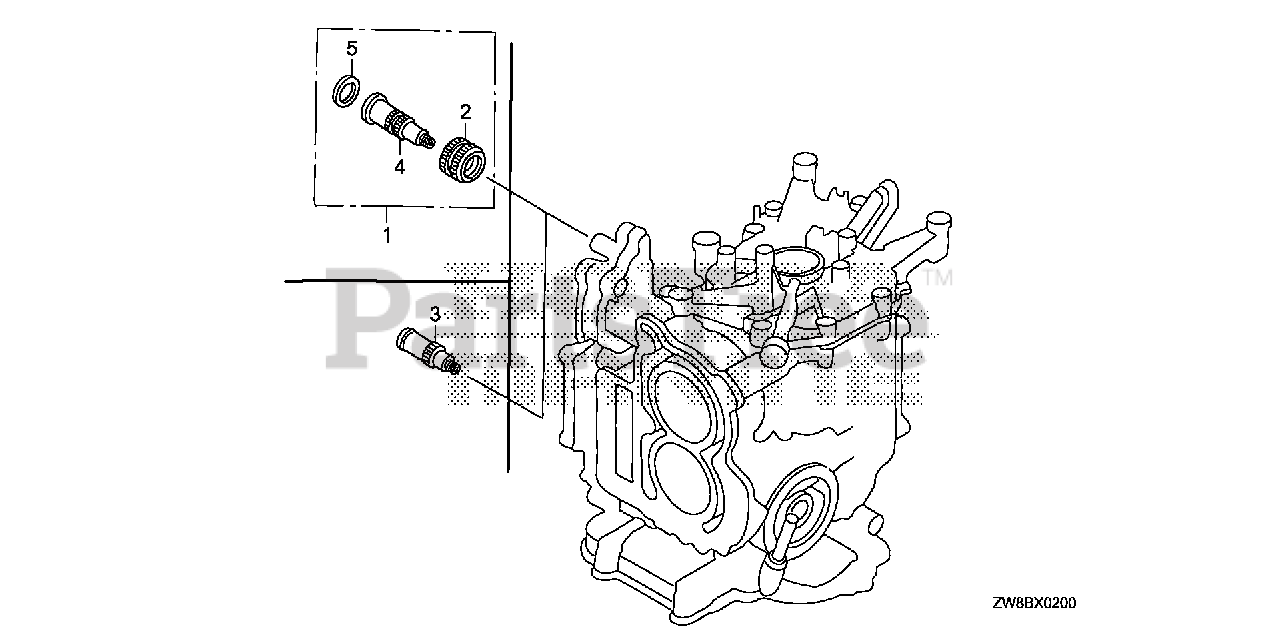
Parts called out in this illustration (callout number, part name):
1	JOINT KIT, WATER HOSE
2	NUT, WATER MOUTH
3	JOINT, WATER HOSE
4	JOINT, WATER HOSE
5	SEAT, WATER MOUTH
